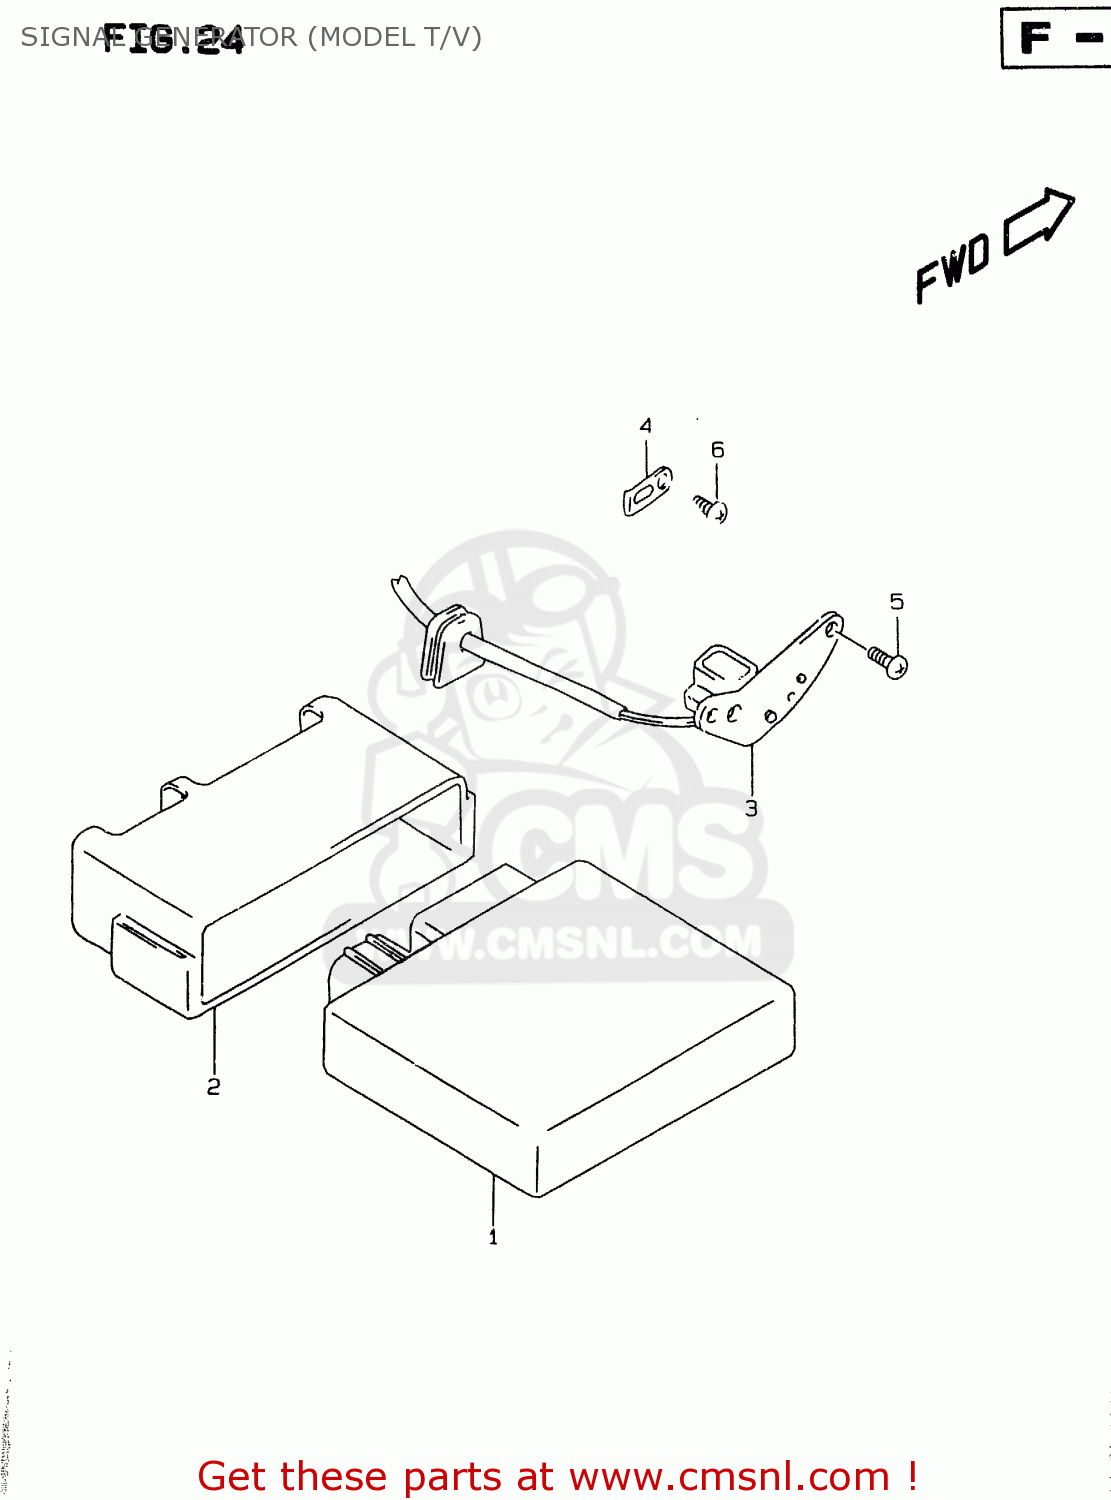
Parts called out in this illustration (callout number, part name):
1	IGNITER ASSEMBLY
2	CUSHION,IGNITER
3	STARTER,SIGNAL GENERATOR
4	CLAMP,SIGNAL GENERATORERATOR
5	SCREW
6	SCREW
